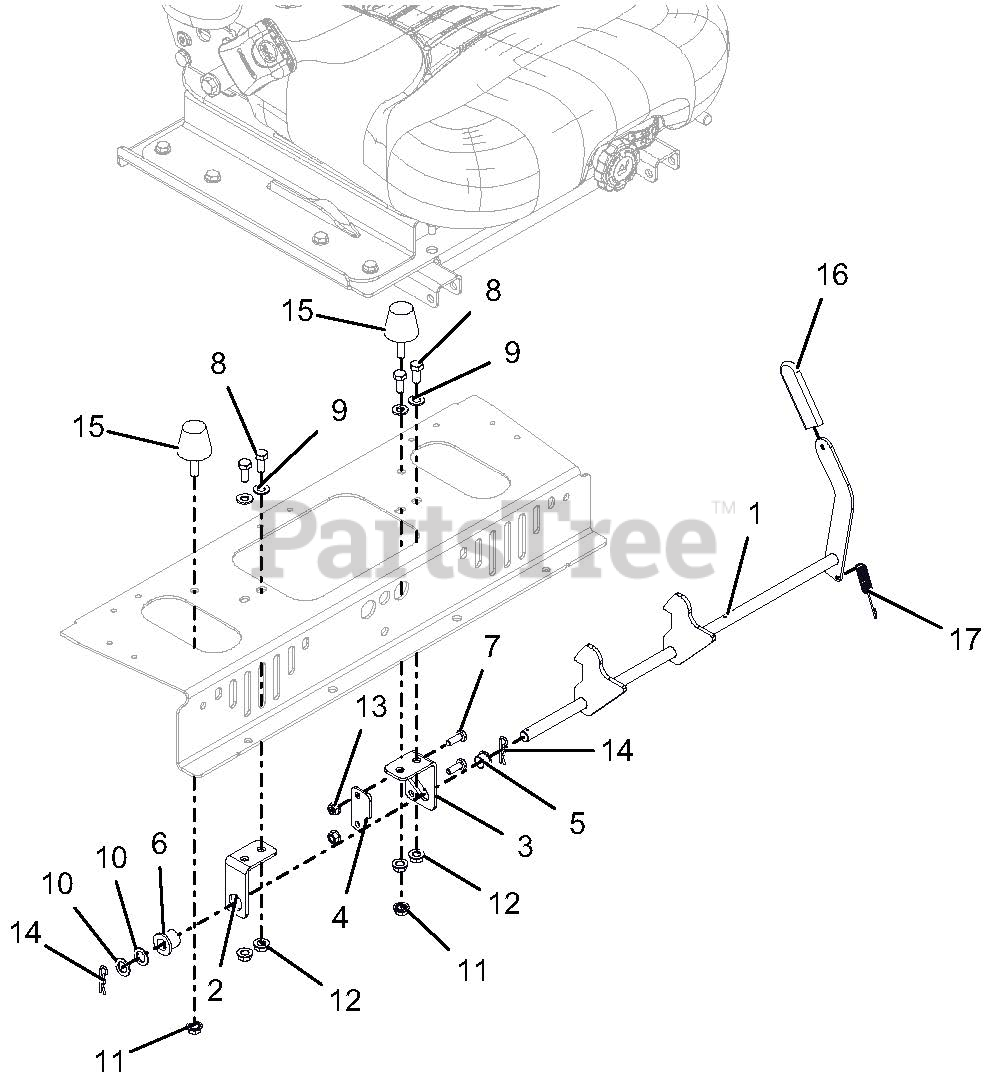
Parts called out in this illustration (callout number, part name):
1	WMT, SEAT LATCH
2	MOUNT, SEAT LATCH - RH
3	MOUNT, SEAT LATCH - LH
4	RETAINER-SEAT LATCH
5	BUSHING, POLYLINER - .50 SPLIT
6	BSHG, FLANGE .515 X .750 X .745 X 1.00 NYLON
7	BLT-HEX .25-20X.75 GR5 YWZC
8	BLT-HEX .31-18X.75 GR5 YWZC
9	WSHR-FL-STL.344X.688X.065YWZC
10	WSHR-FL-STL .520X.827X.062 YWZC
11	@NUT-SPNLK-FLG .312-18 YWZC
12	NUT, LK-TOP-FLG .312-18 YWZC
13	NUT, LK-TOP-FLG .25-20 YWZC
14	PIN-HAIR INT .08X.38X1.42 YWZC
15	BUMPER, STUD MOUNTED CONE SHAPED
16	GRIP-VINYL-YELLOW .125 x 1.0 x 3.0
17	SPRG, EXTENSION
